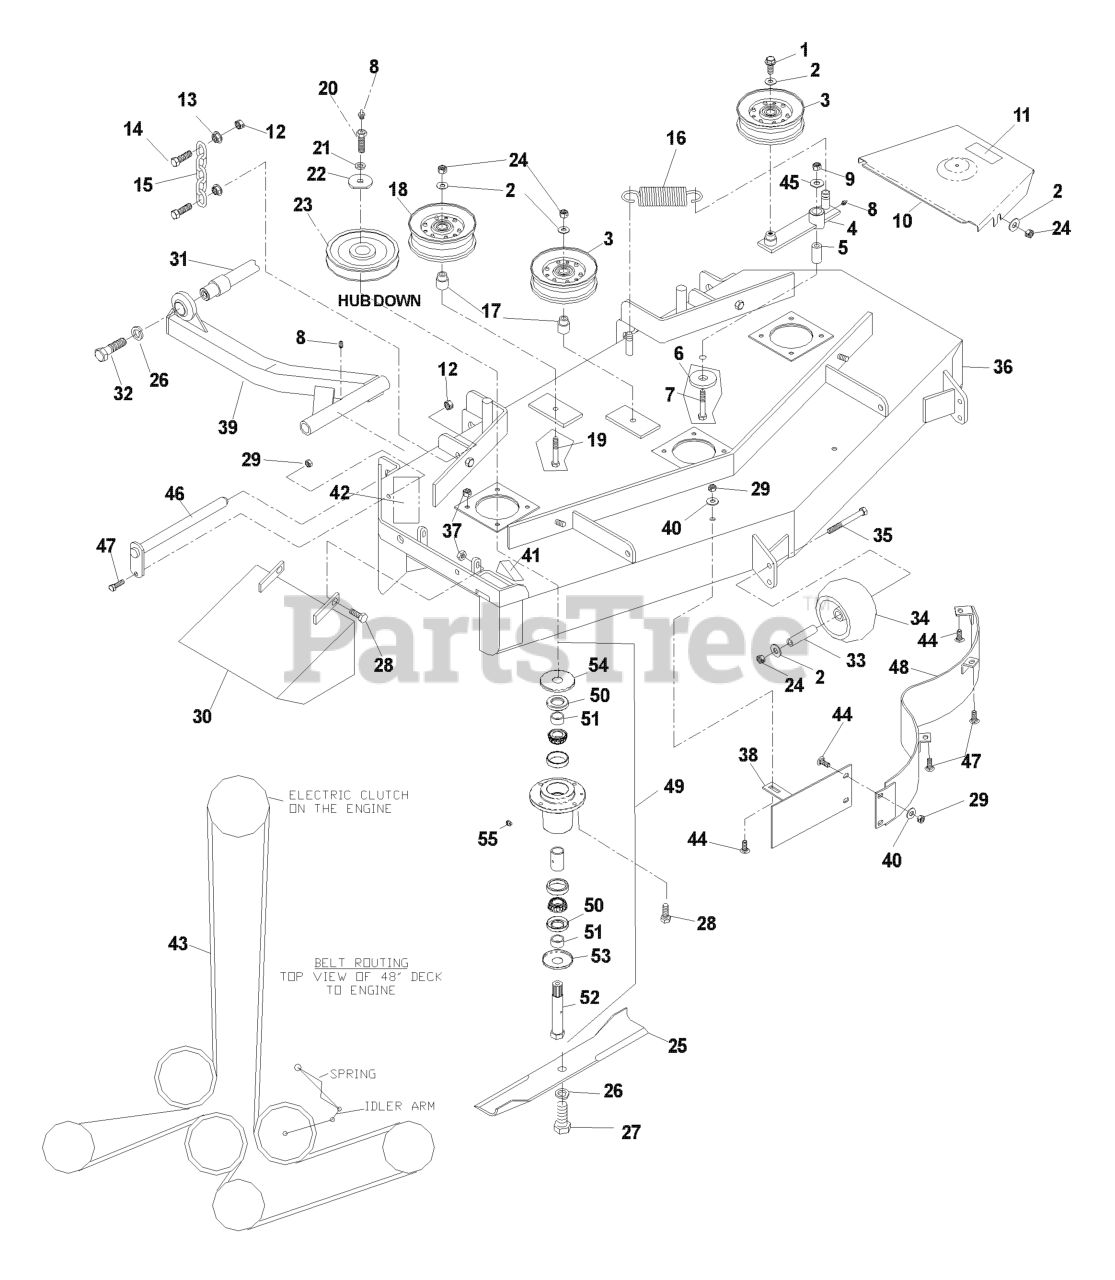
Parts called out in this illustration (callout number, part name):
1	4CS 3/8C X 1 SERRATED HEAD
2	WASHER 3/8 FLAT
3	IDLER PULLEY
5	PIVOT BUSHING
6	WASHER, SUPPORT
7	HCS 1/2C X 3 1/4
8	ZERK
9	NUT 1/2-13 HEX NYLOC ZD
10	LT 48 SHIELD, ORG
11	DECAL, NO STEP
12	NUT 7/16C CENTERLOCK
13	NUT 7/16C WHIZ
14	HCS 7/16C X 1 1/2
15	LIFT CHAIN
17	IDLER BUSHING
18	IDLER PULLEY (TALL)
19	SCREW 3/8C X 2 3/4 HEX CAP
20	DRILLED BOLT 7/16-20 X 1 1/2"
21	WASHER 7/16 LOCK
22	SPINDLE WASHER
23	RP PULLEY - 42/48"
24	NUT 3/8-16 NYLOC
25	BLADE OEM 16 1/4"
26	LOCKWASHER 5/8
27	HCS 5/8F X 1 1/4
28	HCS 5/16C X 1 1/4
29	NUT 5/16C CENTERLOCK
30	CHUTE 48"
31	STRUT MOUNT WELDMENT
32	HCS 5/8C X 2 GR.5
34	ANTI-SCALP ROLLER
35	HCS 3/8C X 3 1/2
36	DECK W/DECALS 48"
37	NUT 5/16 NYLOC
38	CENTER BAFFLE 48"
39	STRUT WLDMT - RT
40	WASHER 5/16 FLAT
41	DECAL, CPSC
42	DECAL, DANGER
43	DECK BELT 48"
44	CARRIAGE BOLT 5/16C X 5/8"
45	WASHER 1/2 FLAT
47	HCS 5/16C X 3/4
48	MAIN BAFFLE - 48" DECK BLK
49	SPINDLE ASSY - 42/48"
50	SHAFT SEAL
52	SPLINED SHAFT - 42/48"
53	BOTTOM DUST CAP
54	TOP DUST CAP
55	PLUG-VENTED
